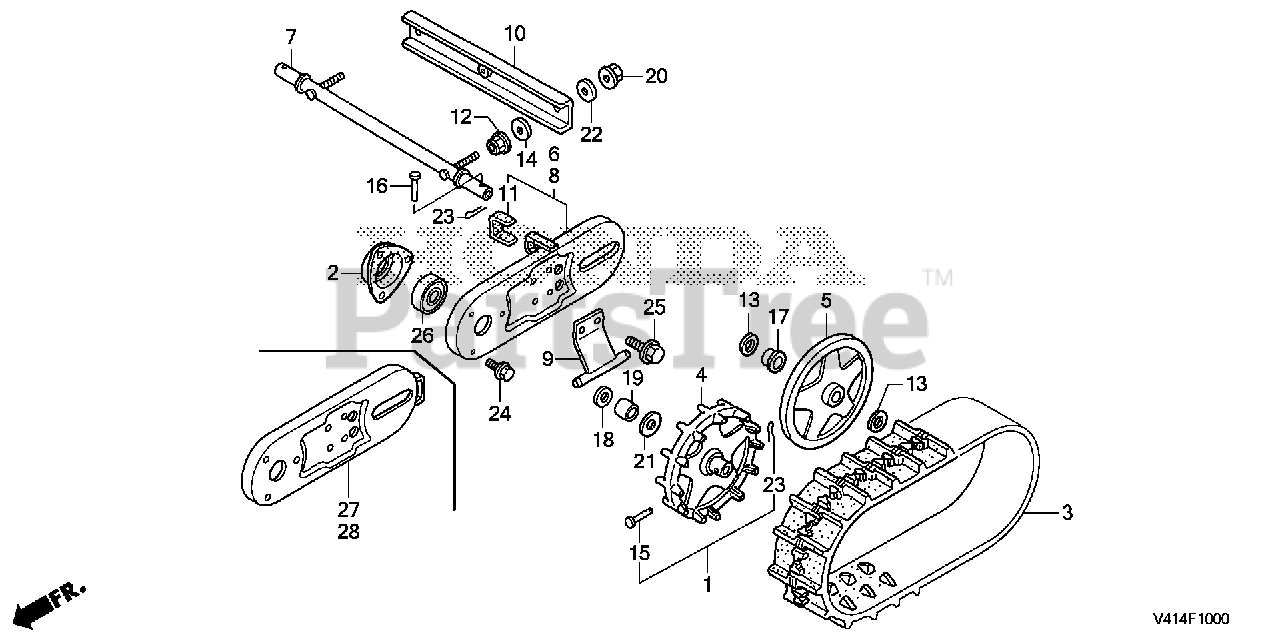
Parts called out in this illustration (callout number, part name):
1	PIN SET, CRAWLER
2	HOLDER, WHEEL SHAFT BEARING
3	CRAWLER (12-60X21) (COO)
3	CRAWLER (12-60X21)
4	SPROCKET, CRAWLER
5	ROLLER, CRAWLER (COO)
5	ROLLER, CRAWLER
7	PIPE, CRAWLER
9	GUIDE, CRAWLER
10	BAR, CRAWLER PLATE
12	NUT, FLANGE (10MM)
13	WASHER, PLAIN (22MM)
14	WASHER, PLAIN (10MM)
15	PIN (6.2X38)
17	COLLAR, CRAWLER PIPE
18	COLLAR, R. WHEEL SHAFT
19	COLLAR, CRAWLER SPROCKET
20	NUT, FLANGE (10MM)
21	WASHER, PLAIN (20MM)
23	PIN, COTTER (3.0X18)
24	BOLT, FLANGE (6X12) Use up to Engine SN 1543277.
25	BOLT, FLANGE (8X14)
26	BEARING, RADIAL BALL (6004UU)
27	PLATE, R. CRAWLER
28	PLATE, L. CRAWLER
